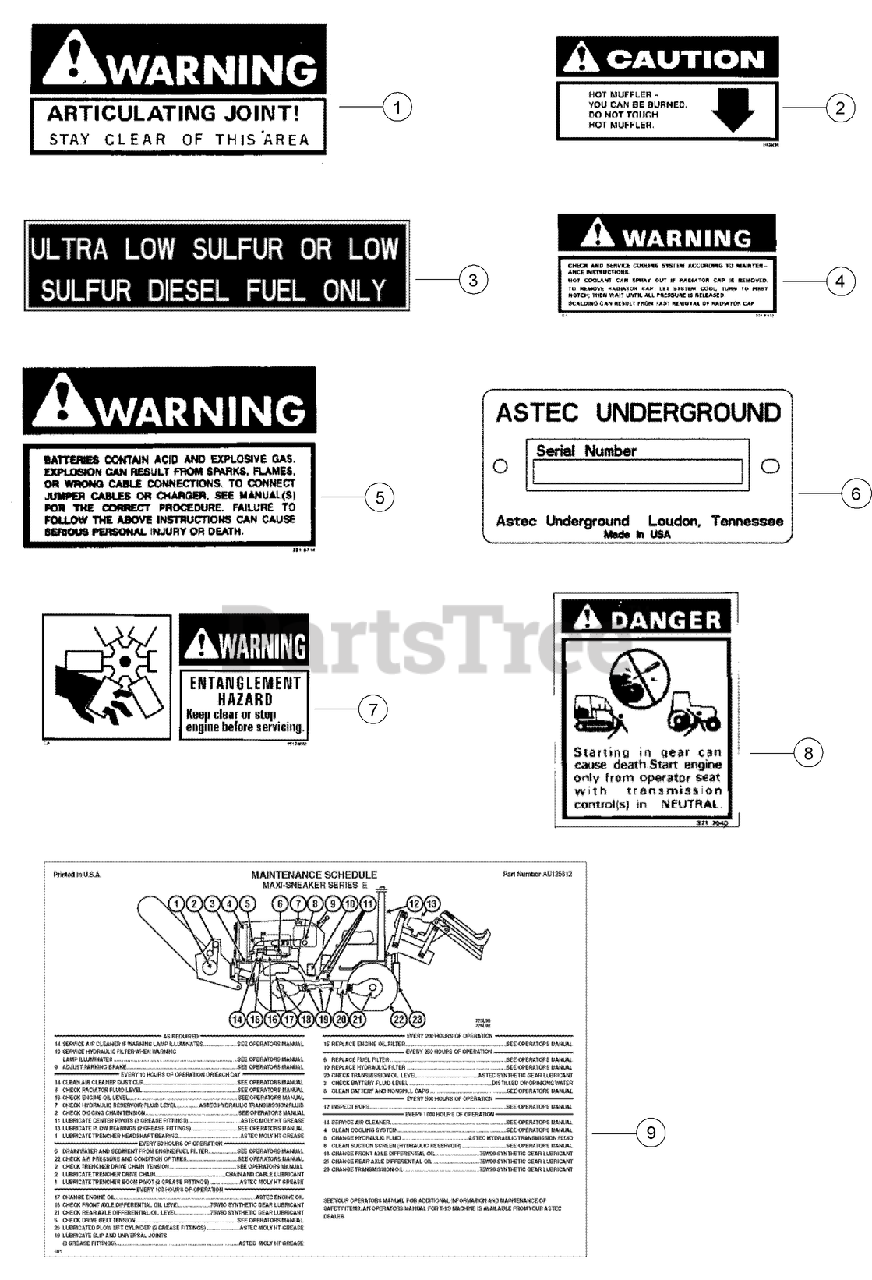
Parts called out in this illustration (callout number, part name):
1	DECAL - Warning, Articulation Joint.
2	DECAL - Caution, Hot Muffler, You Can Be Burned
3	DECAL - Ultra Low Or Low Sulfur Diesel Fuel
4	DECAL - Warning, Check And Service Cooling System
5	DECAL - Warning, Batteries Contain Acid And Explosive Gas
6	PLATE - Serial Number
7	DECAL - Warning, Fan
8	DECAL - Danger, Starting In Gear Can Cause Death
9	DECAL - Maintenance Schedule
